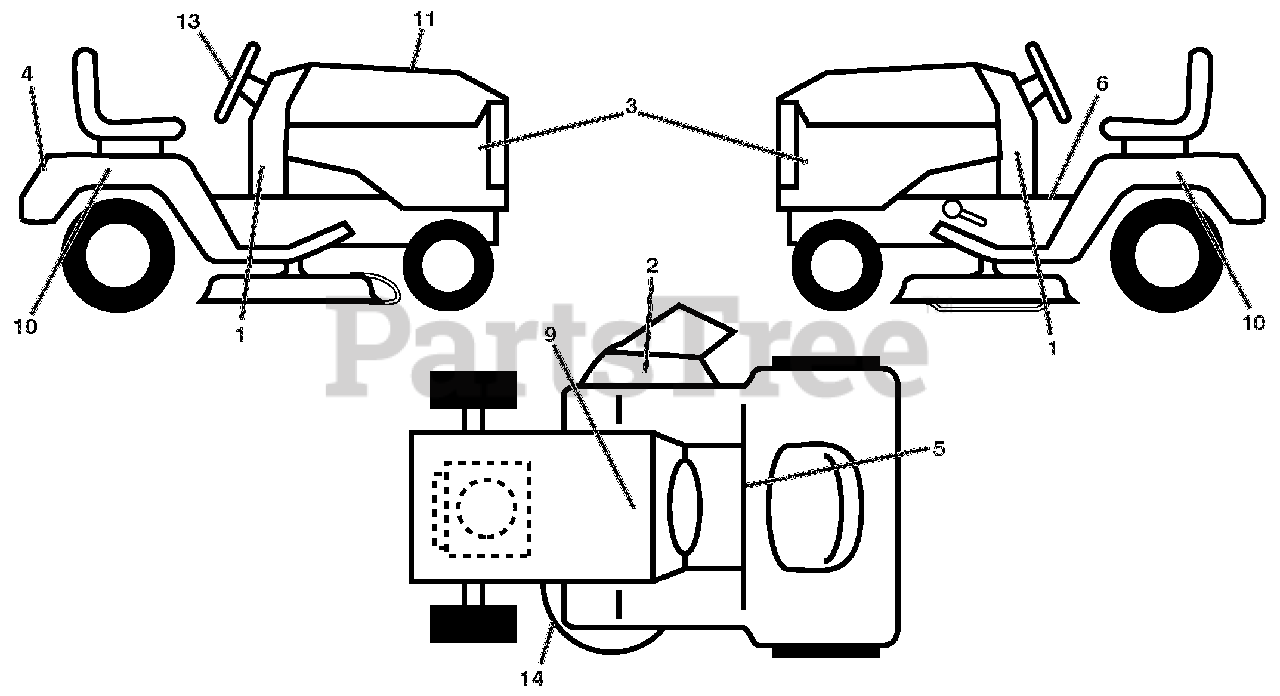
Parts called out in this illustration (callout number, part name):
1	DECAL.DASH
2	DECAL DECK/DEFLECT. WARNING
3	DECAL.SDPNL.PWRDBY KOHL.ARIENS
4	DECAL.FENDER.REAR.ARIENS
5	DECAL.FENDER
6	DECAL, FENDER WARNING
9	DECAL.BAT.DAN/POI P/L SYM.WPN
10	DECAL.FENDER.SIDE.HYDRO.ARIENS
11	DECAL REPLACEMENT
13	DECAL.WHEEL.STEER.ARIENS
14	DECAL.V-BELT.SCH.
